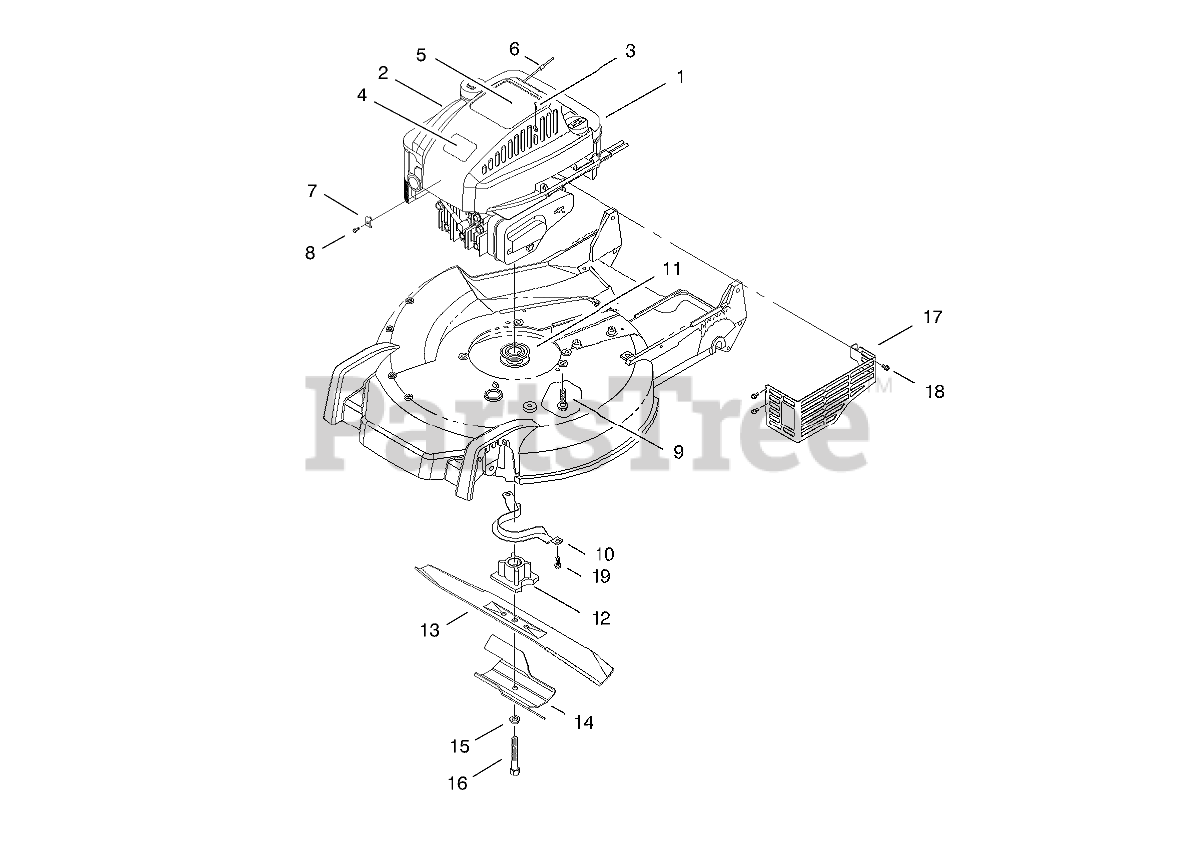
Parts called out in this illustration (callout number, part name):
1	Engine-Quantum 6.0 Hp
2	SHROUD-ENGINE
3	SCREW-PPH
4	PLATE-LOGO
5	DECAL - RECOIL
6	STOP-ROPE
7	CLAMP-CASING
8	SCREW-CLAMP
9	SCREW-HWH
10	Guide-Belt
11	PULLEY-DRIVE, ZONE START
12	RETAINER - BLADE
13	Blade
14	Stiffener-Blade
15	WASHER-LOCK
16	SCREW-BLADE
17	SHIELD-MUFFLER
18	SCREW-HWH
19	SCREW-HWHTF
